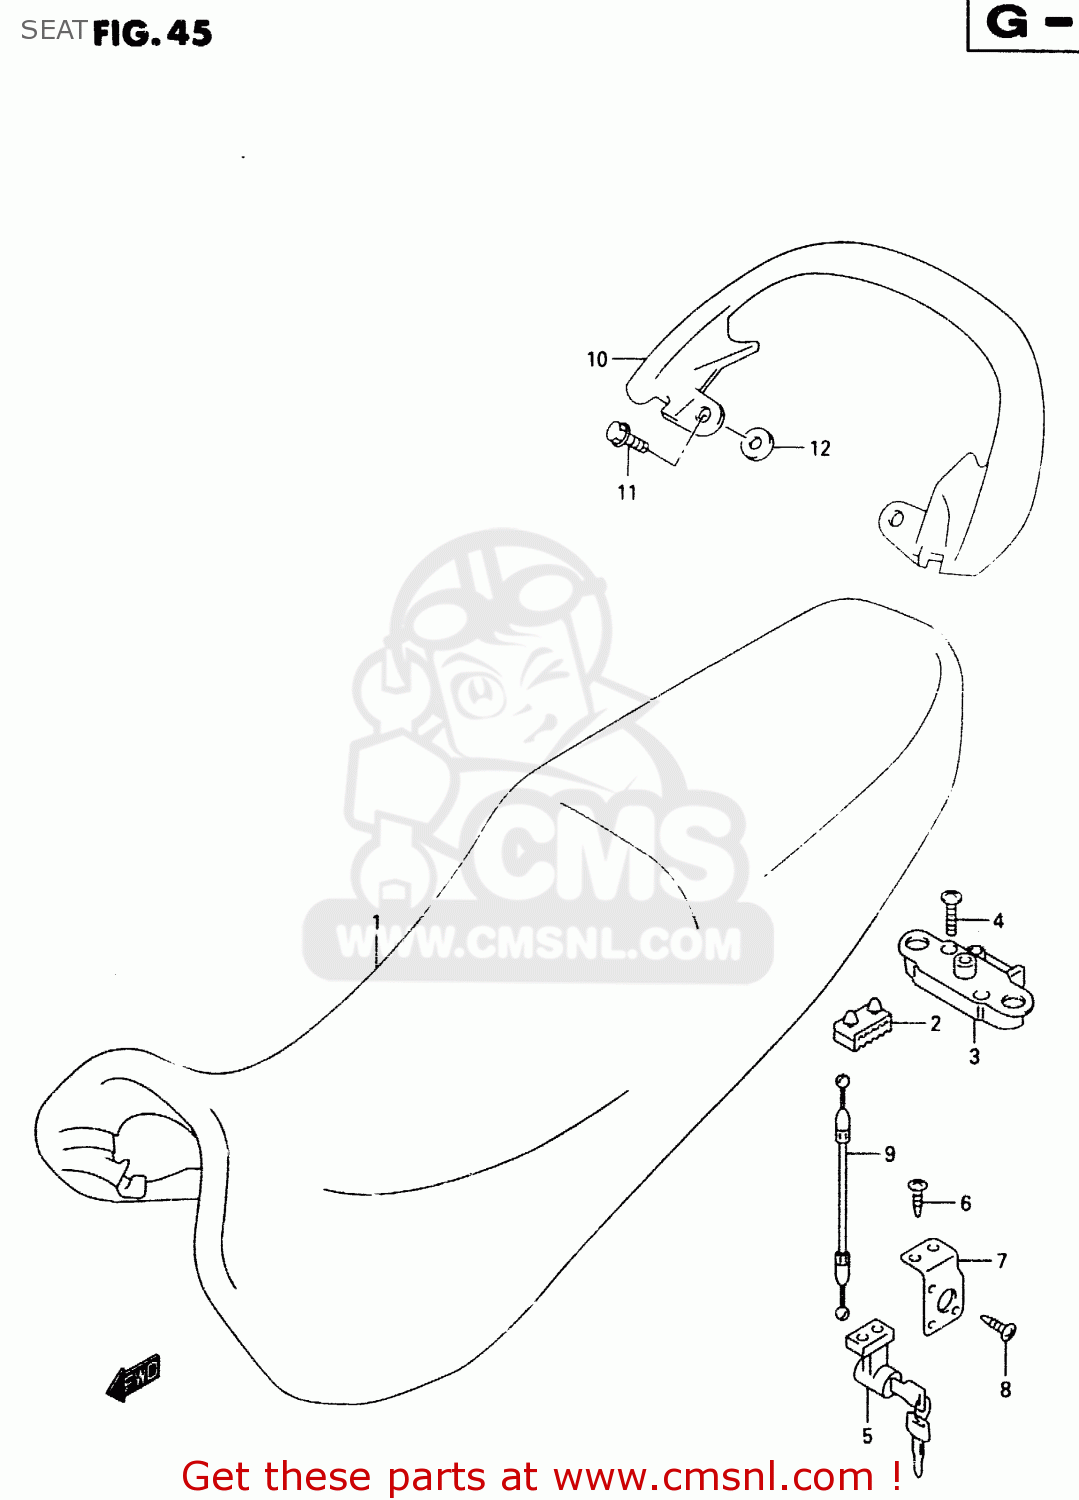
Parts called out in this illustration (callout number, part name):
1	SEAT ASSEMBLY
2	CUSHION,SEAT(40X20X15)
3	BRACKET,SEAT SUPPORT,RIGHT
4	SCREW
5	LOCK SET,SEAT
6	BOLT
7	BRACKET,SEAT LOCK
8	SCREW
9	CABLE,SEAT LOCK
10	HANDLE,PILLION RIDER
11	BOLT
12	CUSHION
